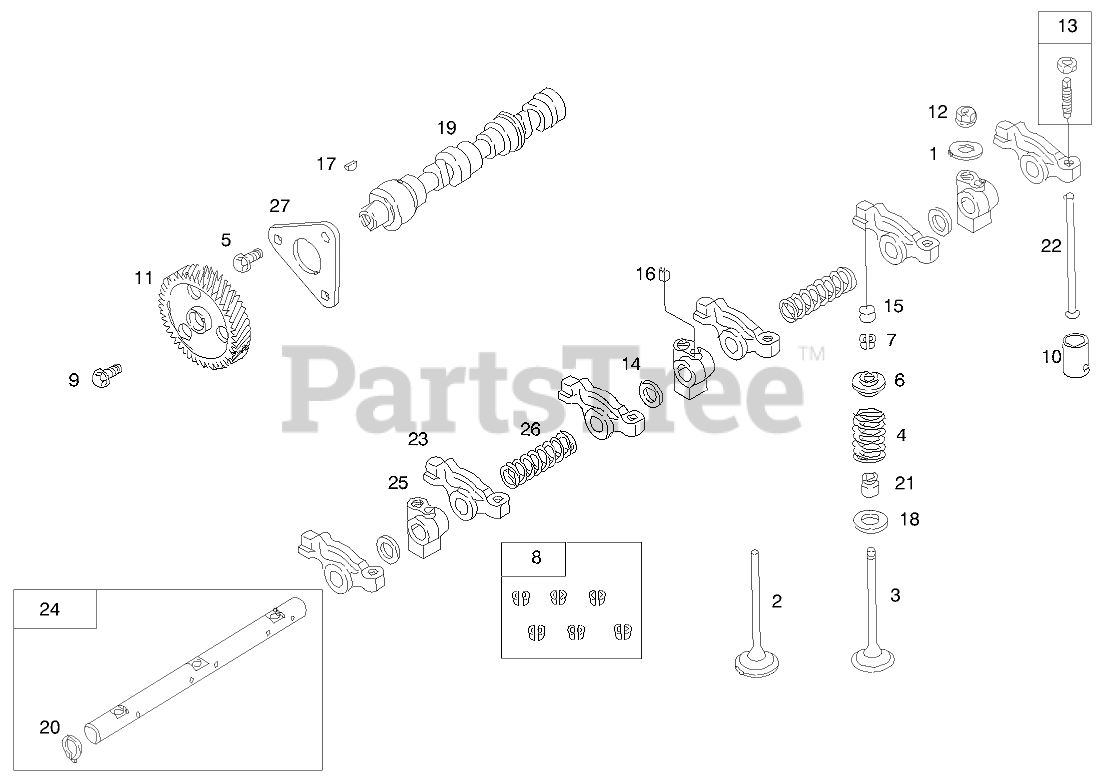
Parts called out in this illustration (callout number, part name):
1	WASHER-FLAT
1	HEAD-CYLINDER
2	VALVE-EXHAUST
3	VALVE-INTAKE
4	SPRING-VALVE
5	SCREW-HEX
6	RETAINER-VALVE
7	KEEPER-VALVE (SET)
8	KEEPER-VALVE (SET OF 6)
8	SWITCH-TEMPERATURE, WATER
9	SCREW-METRIC
9	GASKET-SET
10	TAPPET-VALVE
11	GEAR-CAM
12	NUT-HEX, METRIC
13	ADJUSTER-ARM, ROCKER
14	WASHER-SPACER
14	KIT-VALVE OVERHAUL
15	CAP-VALVE
15	SHAFT-GEAR
16	SCREW-METRIC
17	Key-Timing
18	SEAT-SPRING, VALVE
19	SHAFT-CAM
20	RETAINER
21	SEAL-VALVE
22	ROD-PUSH
23	ARM-ROCKER
24	SHAFT-ARM, ROCKER
25	SUPPORT-ARM, ROCKER
26	SPRING-SHAFT, ROCKER
27	RETAINER-CAMSHAFT
